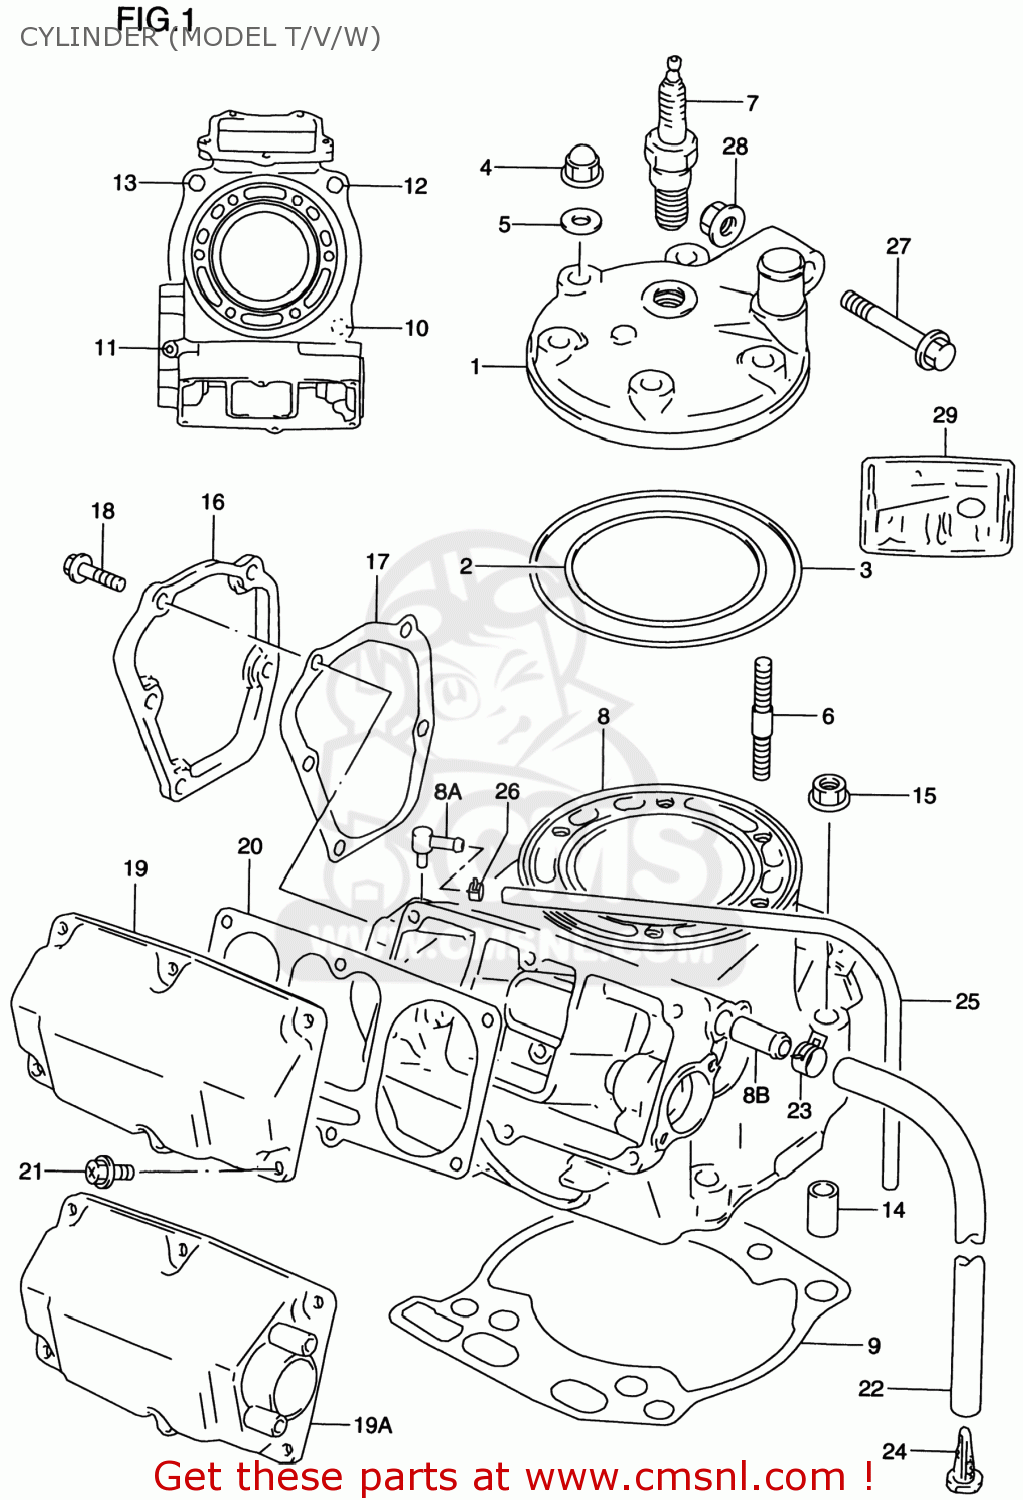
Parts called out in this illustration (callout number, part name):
1	HEAD,CYLINDER
2	O RING,CYLINDER HEAD NO.1
3	O RING,CYLINDER HEAD NO.2
4	NUT
5	GASKET(8.5X17X2.3) (NAS)
6	BOLT,STUD
7	PLUG,SPARK(R6918B-7)
8	CYLINDER SET
8A	UNION,BREATHER HOSE
8B	UNION
9	GASKET,CYLINDER (NAS)
10	STUD 10X30
11	STUD BOLT (L:40)
12	STUD,M10X1.25X
13	STUD BOLT
14	PIN(13X10.4X20)
15	NUT
16	COVER,CYLINDER NO.1
17	GASKET,CYLINDER COVER NO.1 (NAS)
18	BOLT
19	COVER,CYLINDER NO.2
19A	COVER,CYLINDER NO.2
20	GASKET,CYLINDER COVER NO.2
21	BOLT
22	HOSE
23	CLIP
24	FILTER,EXH VALVE BREATHER HOSE
25	HOSE(5X8.2X600)
26	CLIP
27	BOLT(10X48)
28	NUT
29	GASKET SET (NAS)
